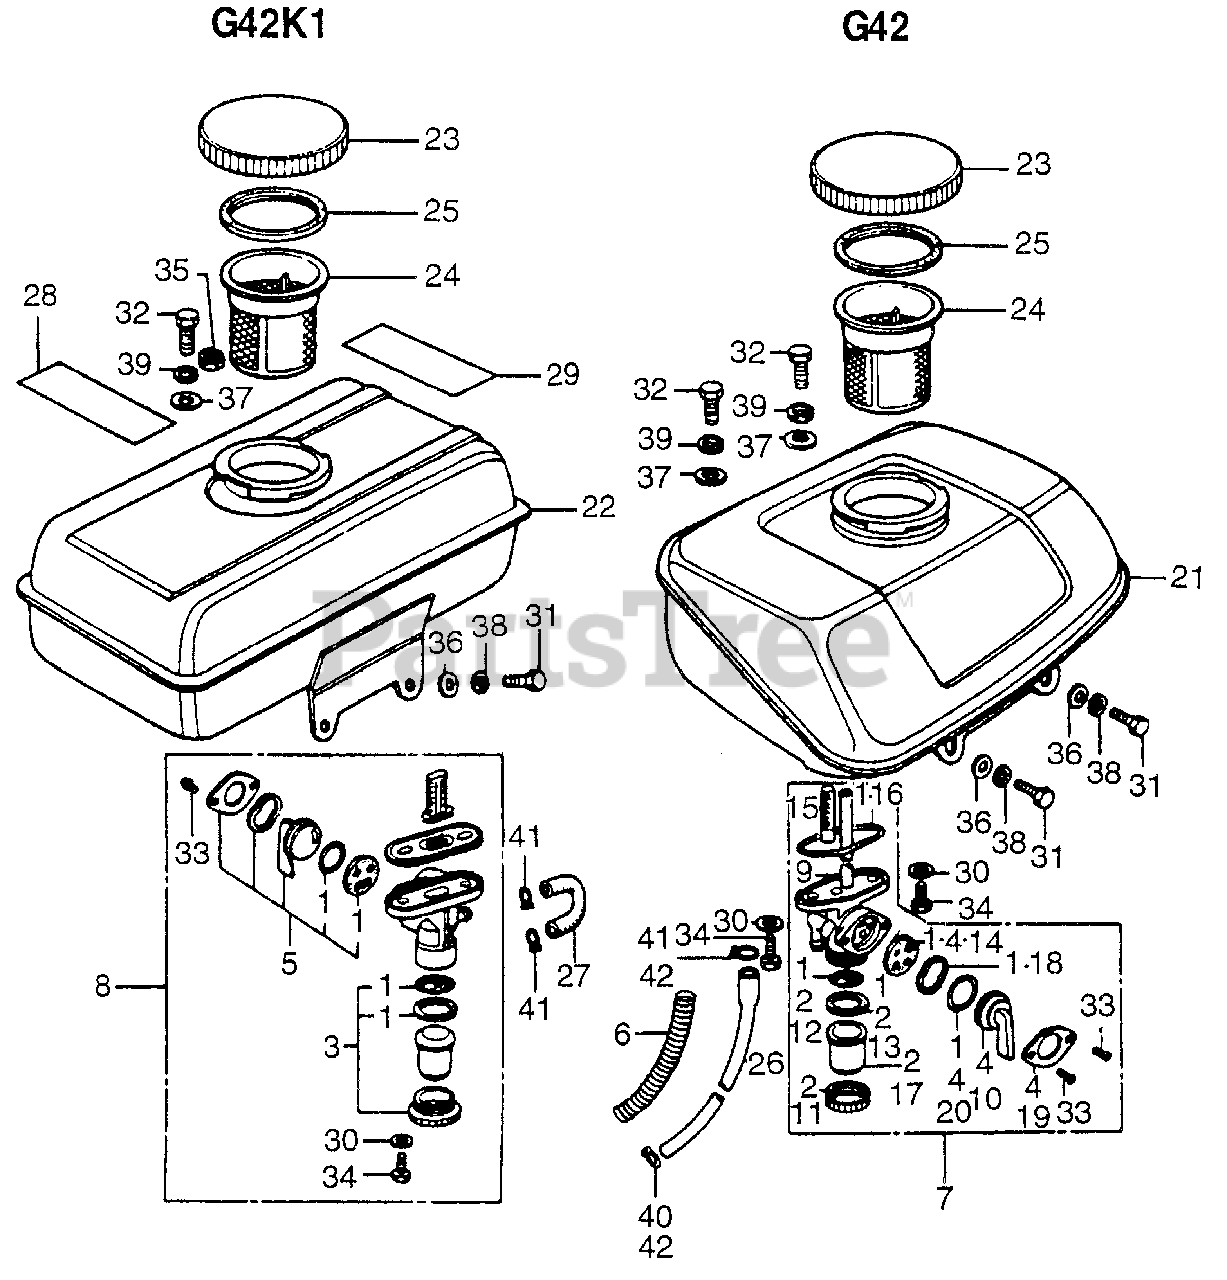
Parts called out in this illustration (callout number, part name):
1	GASKET SET, VALVE
2	CUP SET, STRAINER
4	LEVER SET, VALVE
6	SPRING, FUEL TUBE (NOT AVAILABLE)
7	PETCOCK ASSY. (N/A: SEE COMPONENTS)
9	PETCOCK ASSY.
10	LEVER, VALVE
11	NUT, RING (NOT AVAILABLE)
12	GASKET SET, VALVE
13	GASKET, FUEL STRAINER CUP
14	GASKET, VALVE
15	STRAINER (UPPER) (NOT AVAILABLE)
16	RING, PETCOCK SEAL
17	CUP SET, STRAINER
18	SPRING, LEVER (NOT AVAILABLE)
19	STOPPER, LEVER
20	O-RING (21MM) (NOT AVAILABLE)
21	TANK, FUEL *NH31* (MCKINLEY WHITE)
23	CAP, FUEL TANK (NOT AVAILABLE)
24	FILTER, FUEL
25	GASKET, FUEL FILTER (NOT AVAILABLE)
26	TUBE, FUEL (4.5) (NOT AVAILABLE)
26	BULK HOSE, FUEL (7.5X8000) (7.3X290)
30	GASKET, FIBER (6MM)
31	BOLT, HEX. (6X16)
32	BOLT, HEX. (8X20)
33	SCREW, PAN (3X8)
34	SCREW, PAN (6X16)
36	WASHER, PLAIN (6MM)
37	WASHER, PLAIN (8MM)
38	WASHER, SPRING (6MM)
39	WASHER, SPRING (8MM)
40	CLIP, TUBE (B8)
41	CLIP, TUBE (B10)
42	CLIP, TUBE (B12)
